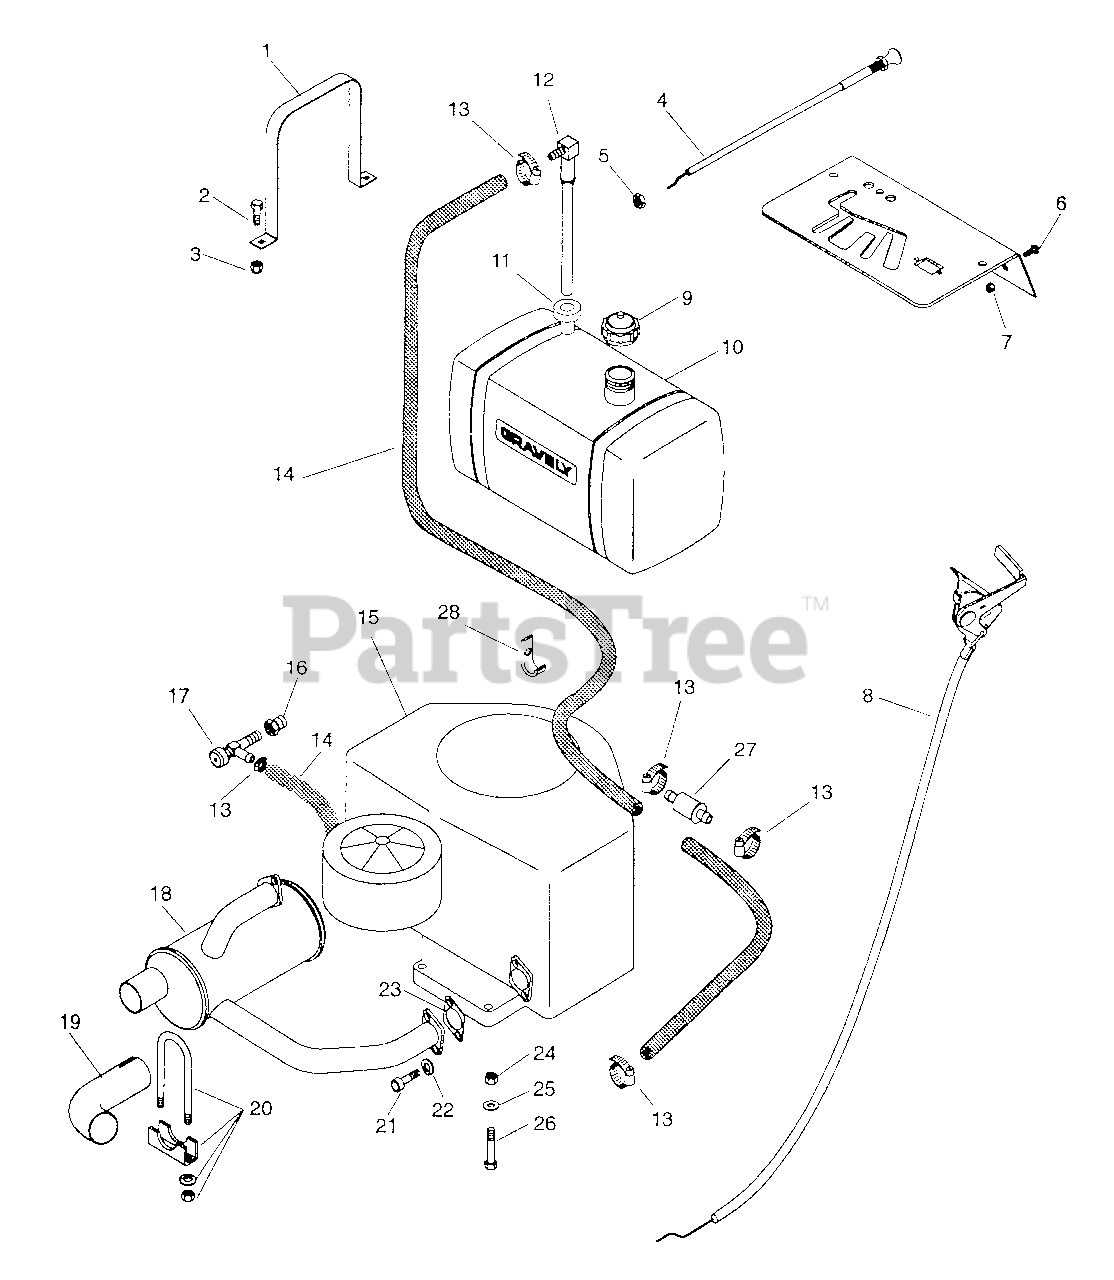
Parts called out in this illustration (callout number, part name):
1	Strap, Fuel Tank
2	Bolt-Hex .25-20 x .63
3	Nut-Locking-Nylon .250-20 Grade 2
4	Control, Choke
4	Cable, Choke
5	Nut-Jam .375-24
6	Screw-Machine 10-32 x .50
7	Nut-Locking 10-32
8	Assembly Throttle Control Cable
8	Throttle Control Cable Assembly
9	Cap, Fuel Tank
10	Tank, Fuel Gravely Pro
12	Fitting, Tank
13	Hose Clamp
14	Gas Line - Bulk 2
15	Engine 18 HP Magnum
15	Engine 16 HP Briggs & Stratton
15	Engine 18 HP Kohler CV, OHV, Electric
16	Adapter, Oil Drain
17	Cock, Oil Drain
18	Muffler
18	Heat Shield
19	Deflector
20	Clamp U 1.75
21	Screw-Cap .31-1 8 x .75
22	Washer-Lock .313 x .078
23	Gasket, Exhaust
24	Nut-Locking-Nylon .312-18 Grade 2
25	Washer-Flat-Steel .344 x .688 x .065
26	Bolt-Hex .31-18 x 1.75 Grade 5
27	Filter, Fuel
28	J-Clamp
